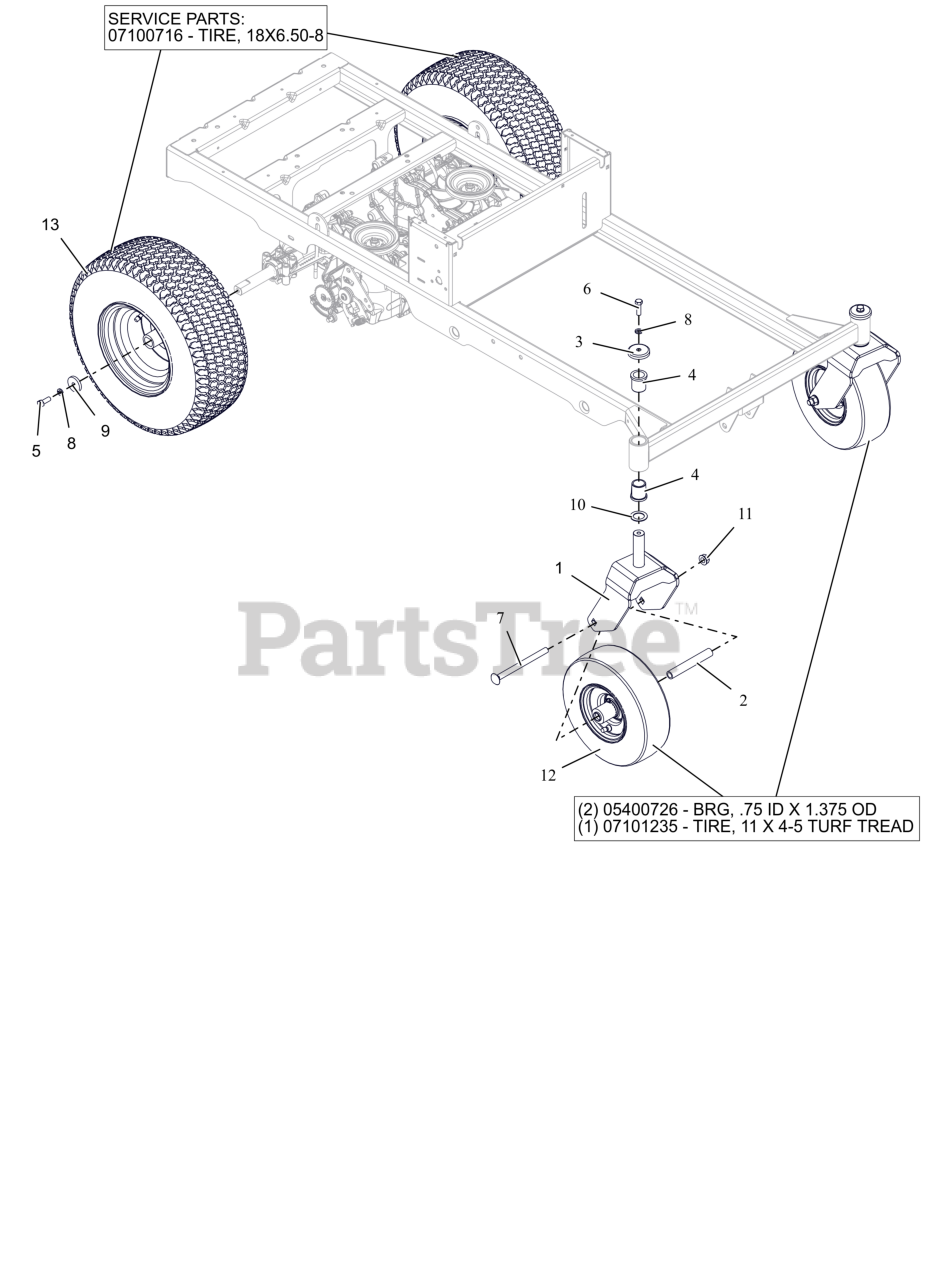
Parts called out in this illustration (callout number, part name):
1	WLDMT- CASTER FORK-X
2	SPACER, ROLLED WHEEL
3	SHIELD, AXLE BEARING
4	BSHG-FLG 1.00X1.25X1.50X1.50
5	BLT, HEX .38-16X1.00 G8ZCCEP30
6	BLT, HEX .38-16X1.25 G5 ZCC
7	BLT, RHSN .50-13X6.50 G5 ZCC
8	WSHR,LK-REG .375X.094 ZCC
9	WSHR, FLT .406X1.50X.245 ZCC
10	WSHR-HRD-THRS 1.007X1.542X.062
11	NUT-LK-CTR-FLG .500-13 GG ZCC
12	ASM, WHL/TIRE 11X4.00-5
12	BRG, .75 ID X 1.375 OD
12	TIRE, 11X4-5 TURF TREAD
13	ASM, WHL/TIRE 18X6.50-8 DHUB
13	TIRE, 18X6.5-8
